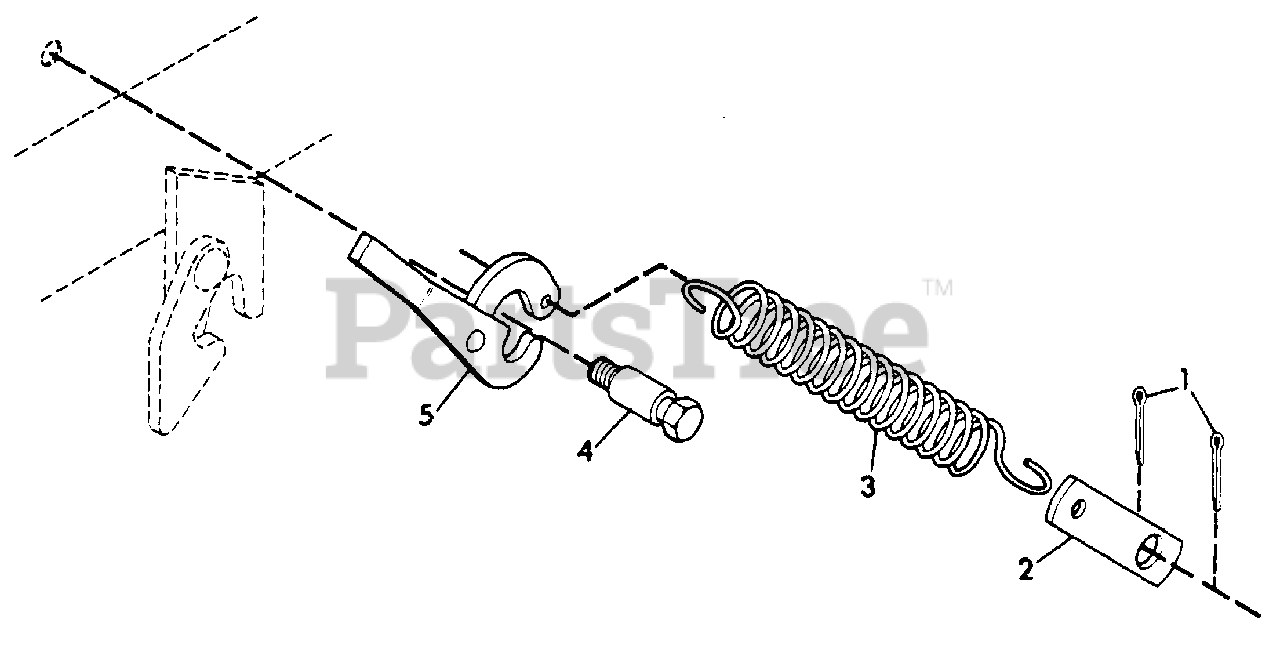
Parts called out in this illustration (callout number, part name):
1	PIN, COTTER .125X1.25
2	STRAP
3	SPRING, EXTENSION 7.625X1.5X70R
4	PIN, LATCH
5	ASSEMBLY, SPRING LATCH L.H.
5	ASSEMBLY, SPRING LATCH R.H.
